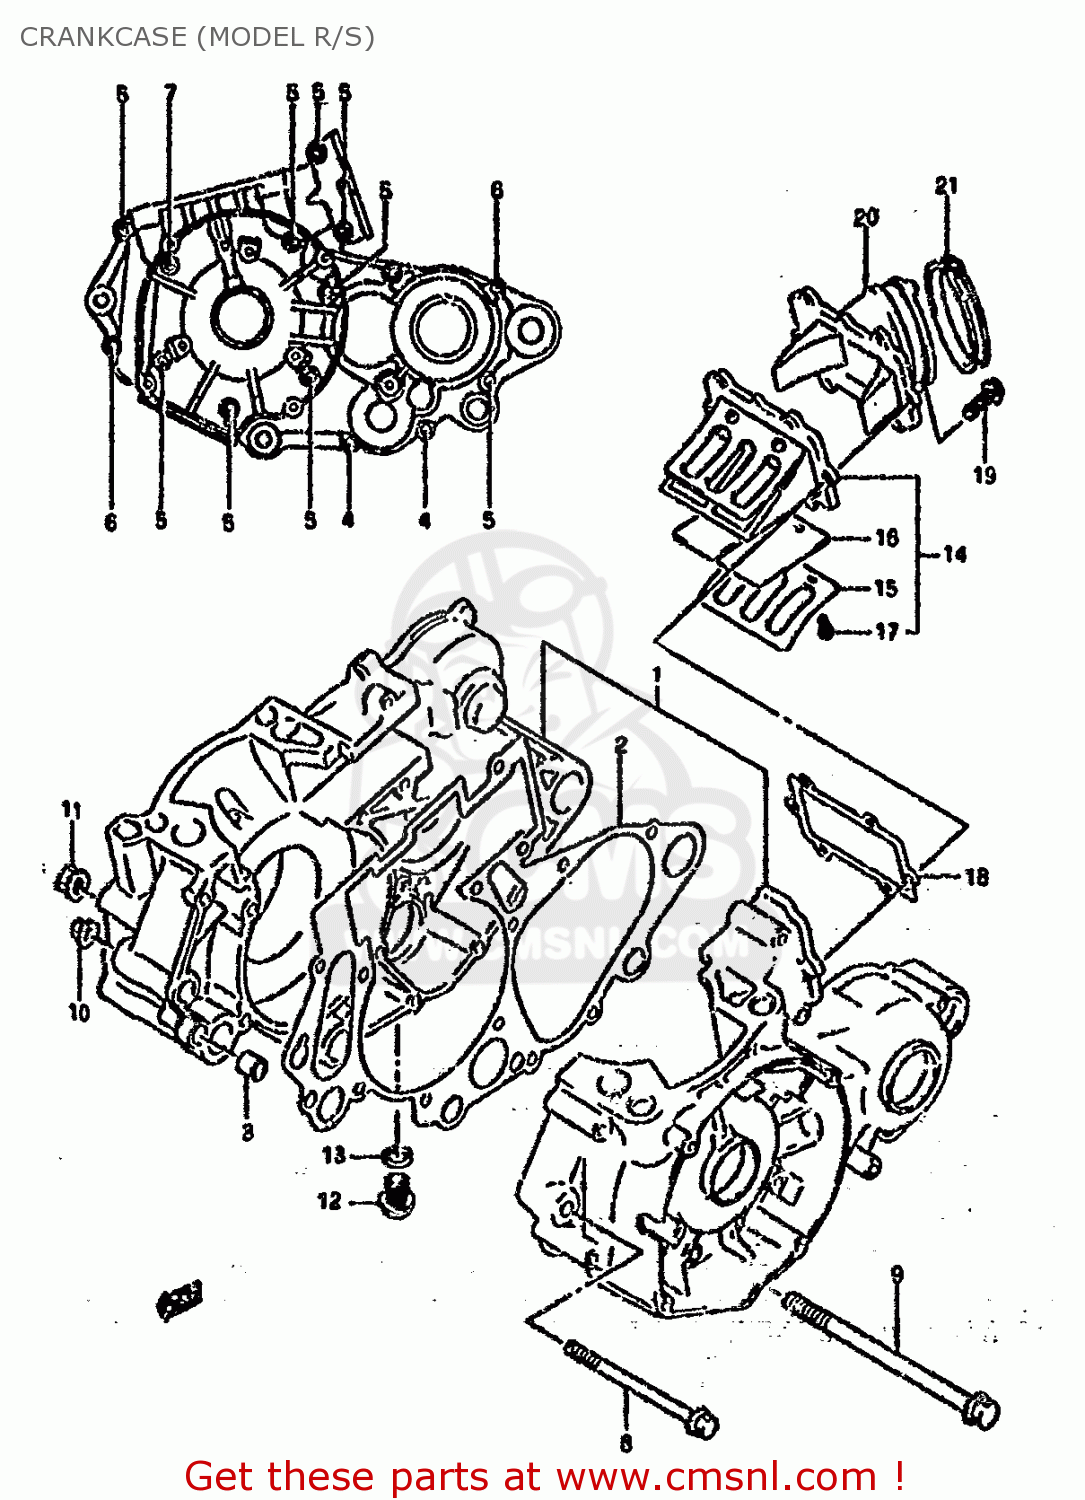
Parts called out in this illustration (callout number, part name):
1	CRANKCASE SET
2	GASKET,CRANKCASE
3	PIN
4	BOLT
5	BOLT
6	BOLT
7	BOLT
8	BOLT(8X102)
9	BOLT(10X140)
10	NUT
11	NUT
12	Bolt
13	GASKET(12.1X16.2X3.7) (NAS)
14	VALVE ASSY,REED
15	STOPPER,REED VALVE
16	VALVE,REED
17	SCREW
18	GASKET,REED VALVE (NAS)
19	SCREW
20	PIPE,INTAKE
21	CLAMP
